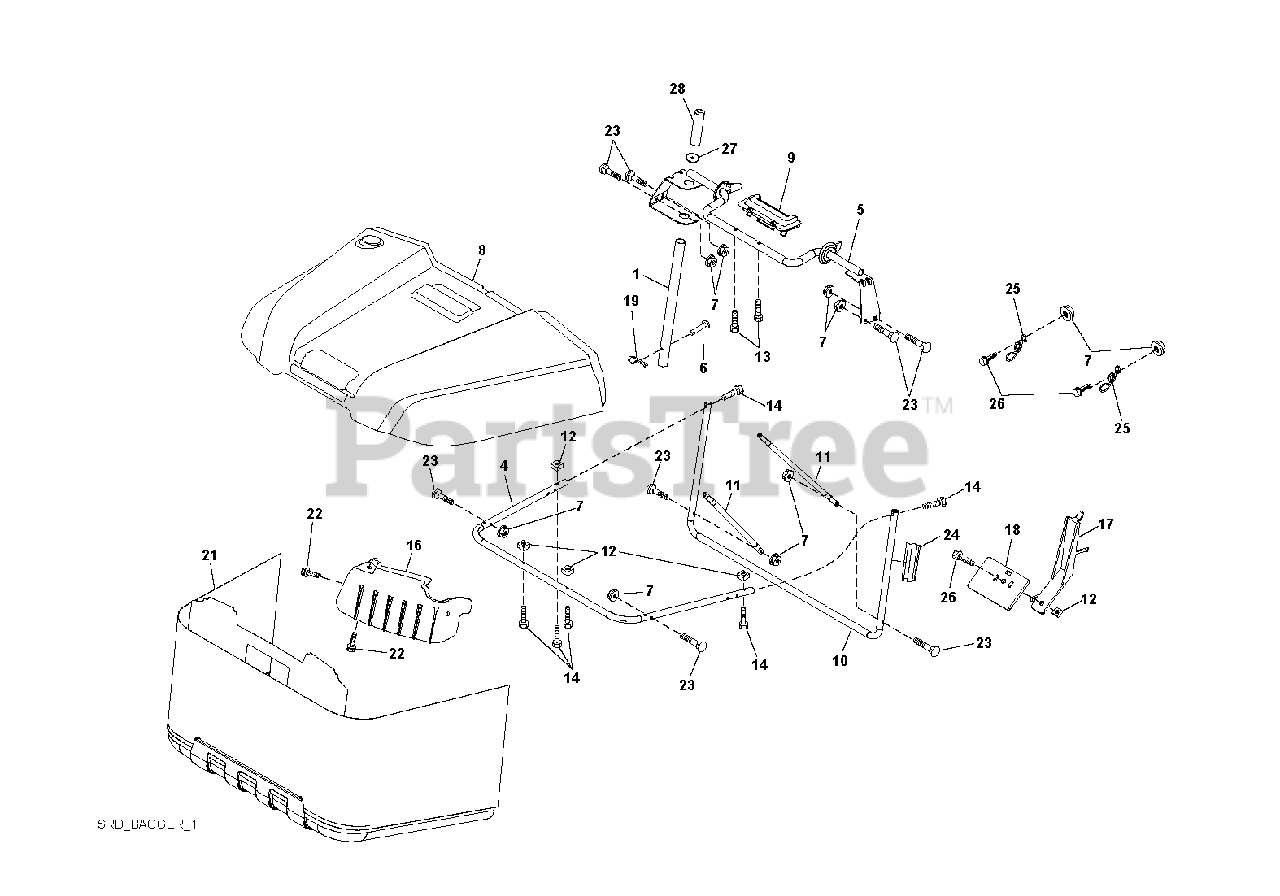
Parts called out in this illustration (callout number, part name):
1	TUBE HANDLE
6	RIVET,DRILLED
7	NUT T
19	RETAINER-SPRNG RB
22	SCREW.HI-LO.CONSOLE
26	SCREW HEX CRT
28	GRIP.HANDLE.BLACK
